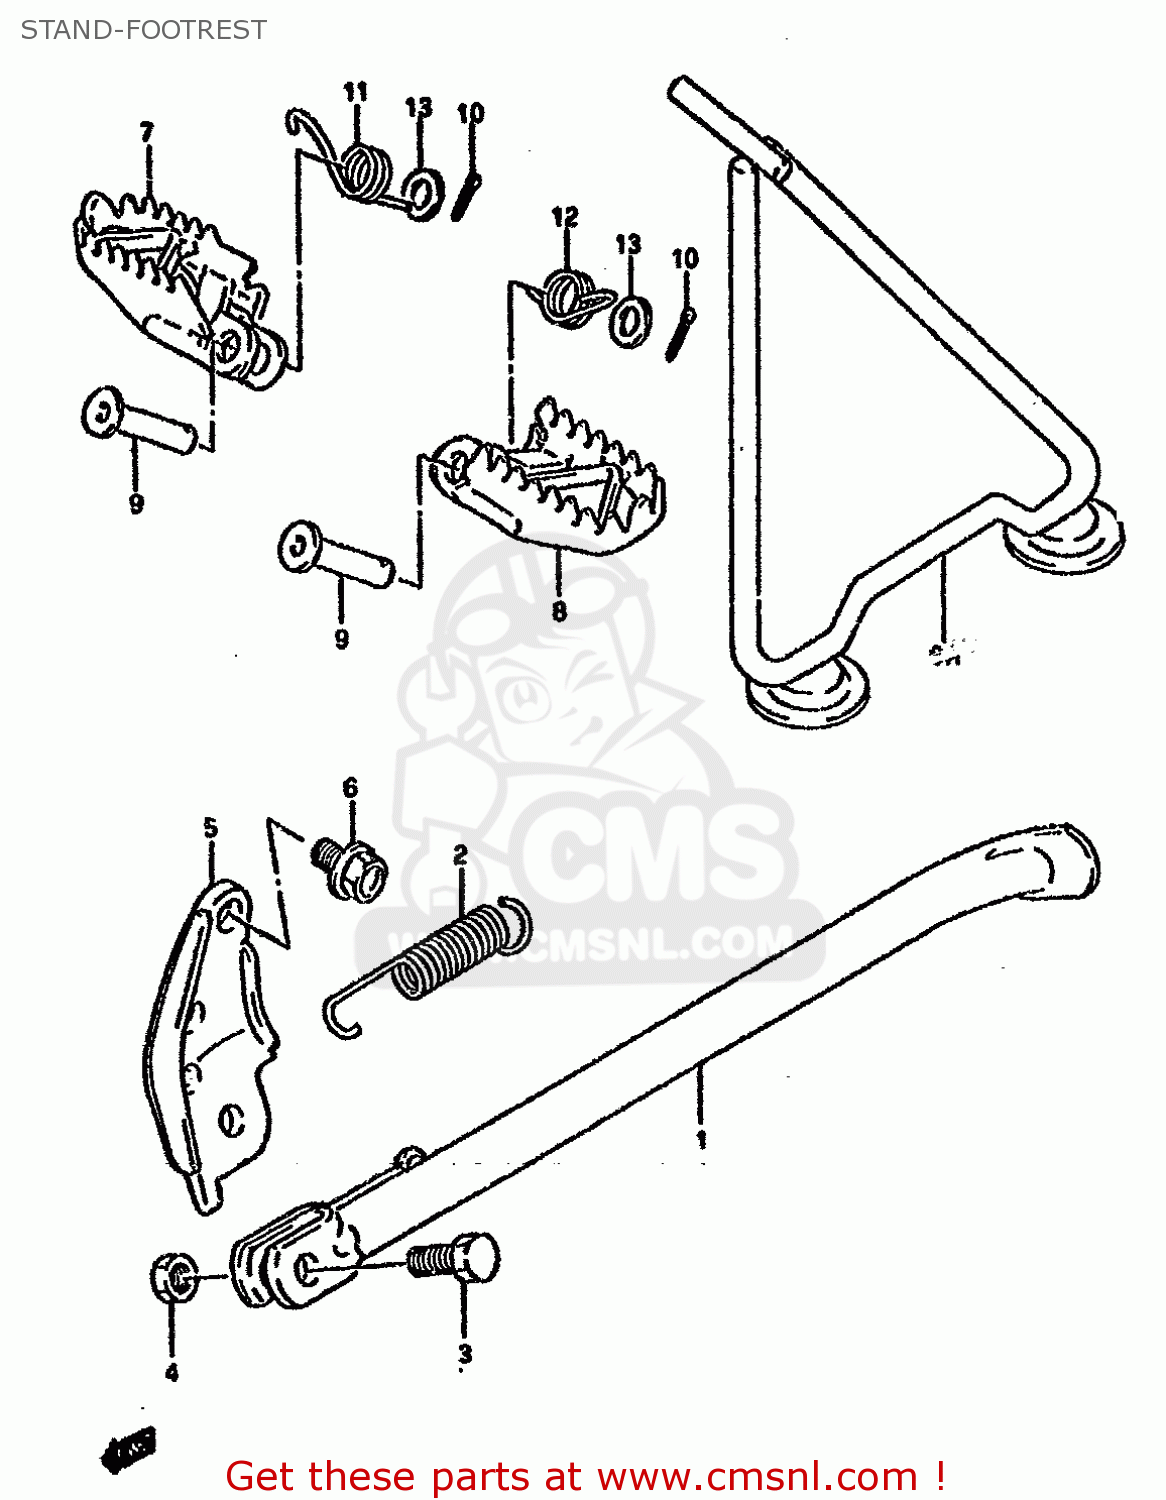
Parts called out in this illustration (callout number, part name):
1	STAND,PROP(BLACK)
2	SPRING
3	BOLT(10X30)
4	NUT
5	BRACKET,PROP STAND(BLACK)
6	BOLT
6A	STAND COMP
7	FOOTREST,R
8	FOOTREST,L
9	PIN(10X41.5)
10	PIN 25X20
11	SPRING
12	SPRING
13	WASHER
